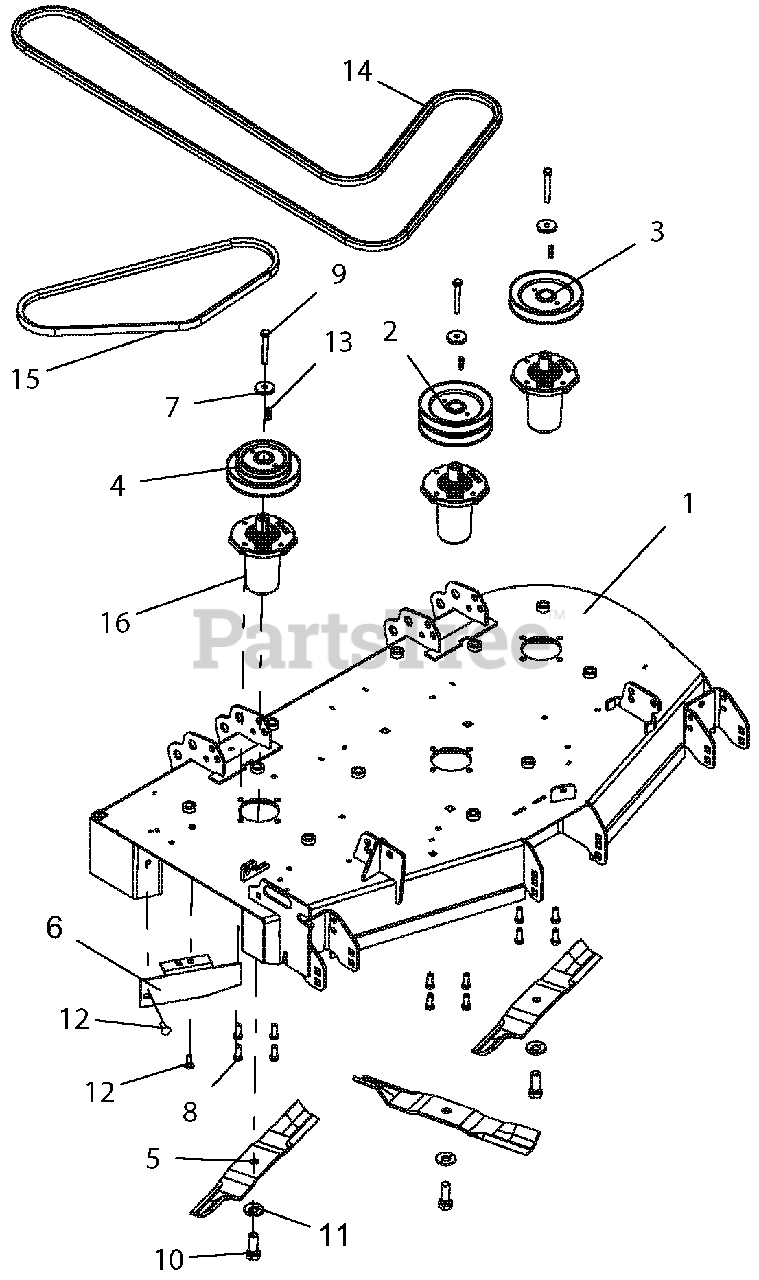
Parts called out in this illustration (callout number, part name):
1	KIT, DECK - 48" W/SAFTEY DECALS
2	PULLEY, DOUBLE-1" ID X 5.75" OD-BLACK
3	PULLEY, V - 1" ID X 5.75" OD-BLACK
4	PULLEY, DOUBLE -1" ID X 5.75" & 4.25" OD
5	BLADE, 16.19" MOWER (HI-LIFT)
6	BAFFLE, DISCHARGE, 44"-48"-RED
7	RETAINER, SHEAVE SPINDLE
8	BLT-HEX .38-16X1.00 GR5 YWZC EP30
9	BLT-HEX .38-16X2.75 GR8 YWZC
10	BLT, HEX .62-18X1.75 GR8 YWZC
11	WSHR, BLVL .63X1.625X.14
12	BLT-RDHDSQSHNK .31-18X1.00 G5 Y
13	KEY-SQ .250X.250X1.00 RC 40-50
14	BELT, BB 118.00 WRAPPED HEX
15	V-BELT, B-RAW EDGE COGGED
16	SERVICE, ASM SPINDLE- DUCTILE
